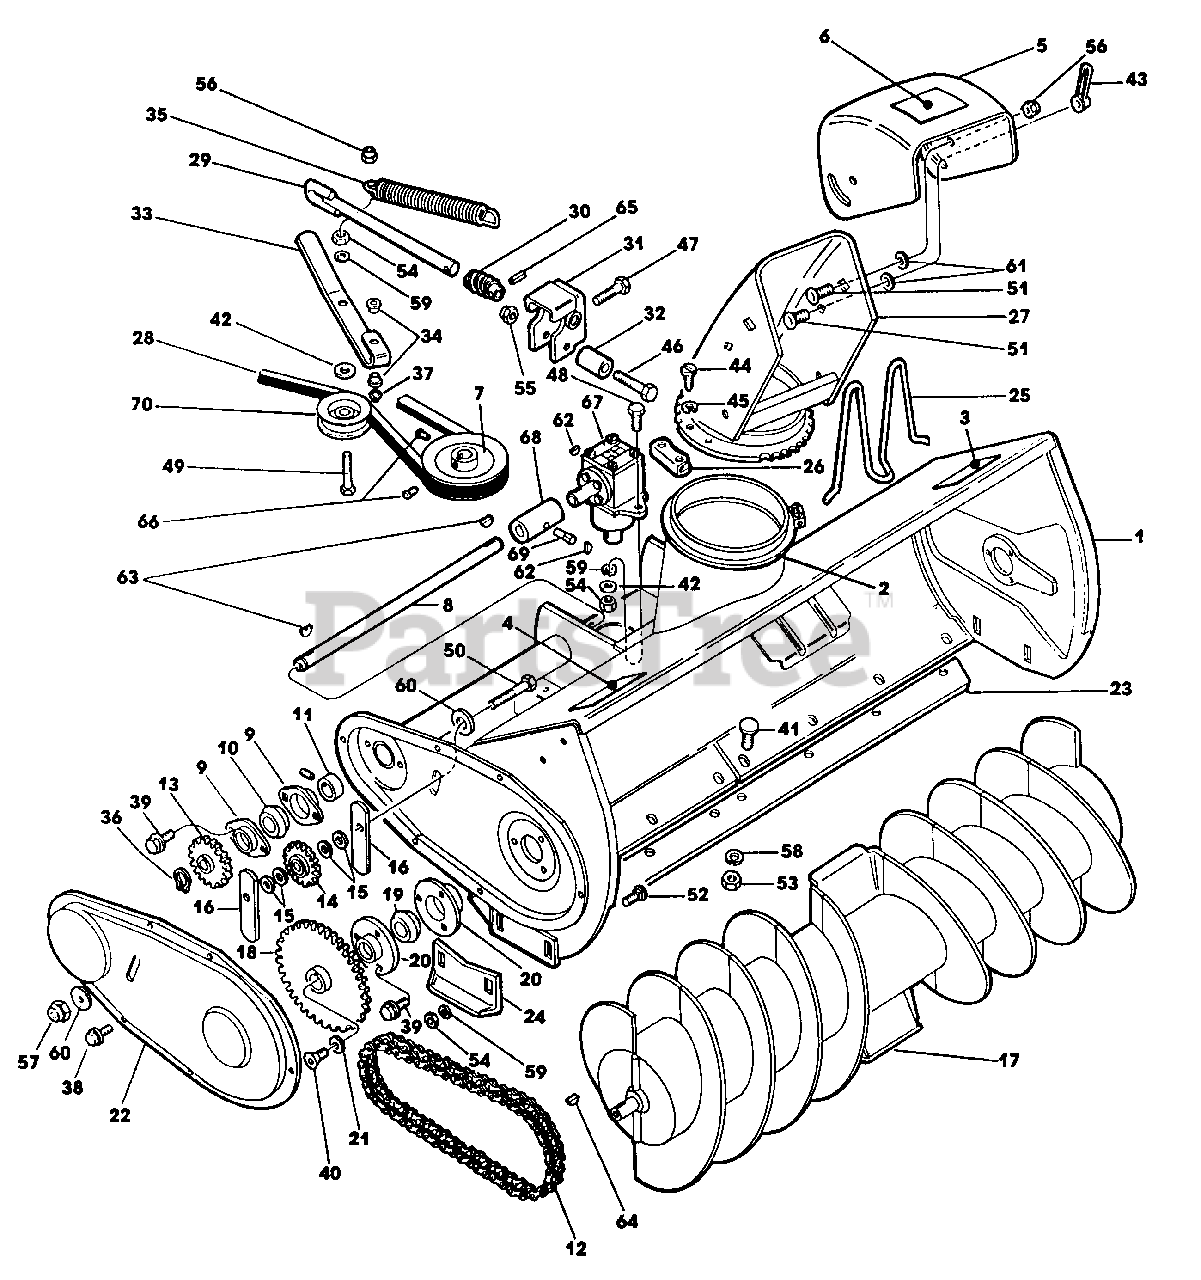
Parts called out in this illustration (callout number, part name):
1	Collector Housing Ass'y. w/Decals
2	Chute Collar
3	Decal-Warning
4	Decal-Danger
5	Chute Deflector & Decal Ass'y
6	Decal-Danger
7	Pulley, 4 1/2" Diameter
8	Output Shaft
9	Flangette Stamping
10	Bearing
11	Collar w/Setscrews
12	Chain
13	Sprocket
14	Idler Sprocket
15	Spacer
16	Strip
17	Auger
18	Sprocket
19	Bearing
20	Flangette Stamping
21	Washer
22	Drive Cover
23	Scraper Blade
24	Skid
25	Discharge Guard
26	Retainer
27	Discharge Chute
28	V-Belt (Secondary)
29	Worm Shaft
30	Worm Gear
31	Worm Support
32	Spacer-Worm Support
33	Idler Arm Assembly w/Bushings
34	Bushing
35	Spring-Idler
36	Snap Ring
37	Snap Ring
38	Lock Screw
39	Lock Screw
40	Flat Socket Hd. Screw
41	Wafer Hd. Bolt
42	Washer, Flat
43	Wing Nut
44	Screw, Self Tapping
45	Lock Washer, #6
46	Cap Screw, Hex Hd
47	Cap Screw, Hex Hd
48	Cap Screw, Hex Hd
49	Cap Screw, Hex Hd
50	Cap Screw, Hex Hd
51	Bolt, Carriage
52	Bolt, Carriage
53	Nut, Hex
54	Nut,Hex
55	Nut, Hex Cone Lock
56	Nut, Hex Cone Lock
57	Nut, Hex Cone Lock
58	Washer, Spring Lock
59	Washer, Spring Lock
60	Washer, Flat
61	Washer, Flat
62	Key, Woodruff
63	Key, Woodruff
64	Key, Woodruff
65	Roll Pin
66	Setscrew, Square Hd. Cup Pt
67	Gear Box, R.H
68	Coupling
69	Drive Pin, Grooved
70	Idler Pulley
